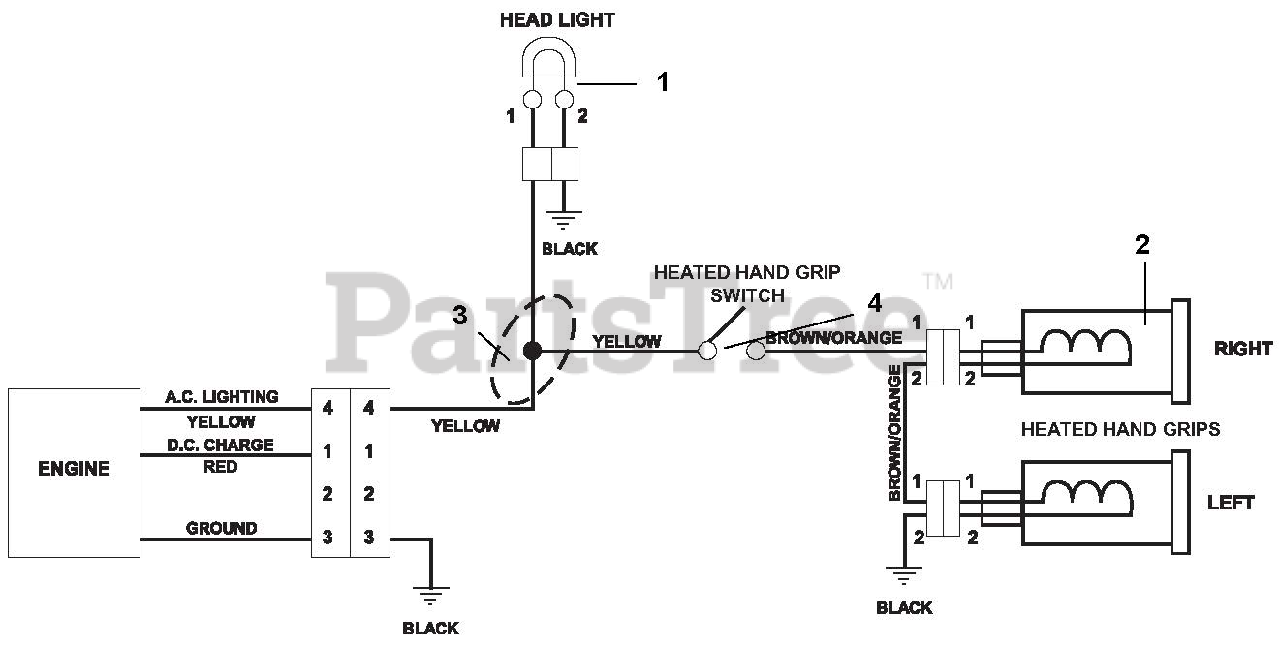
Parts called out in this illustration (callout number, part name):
1	HEADLIGHT ASSY, HALOGEN 20W
2	HEATED GRIP, MAGURA
3	HARNESS, LIGHT & WARMER
4	SWITCH, ON/OFF
